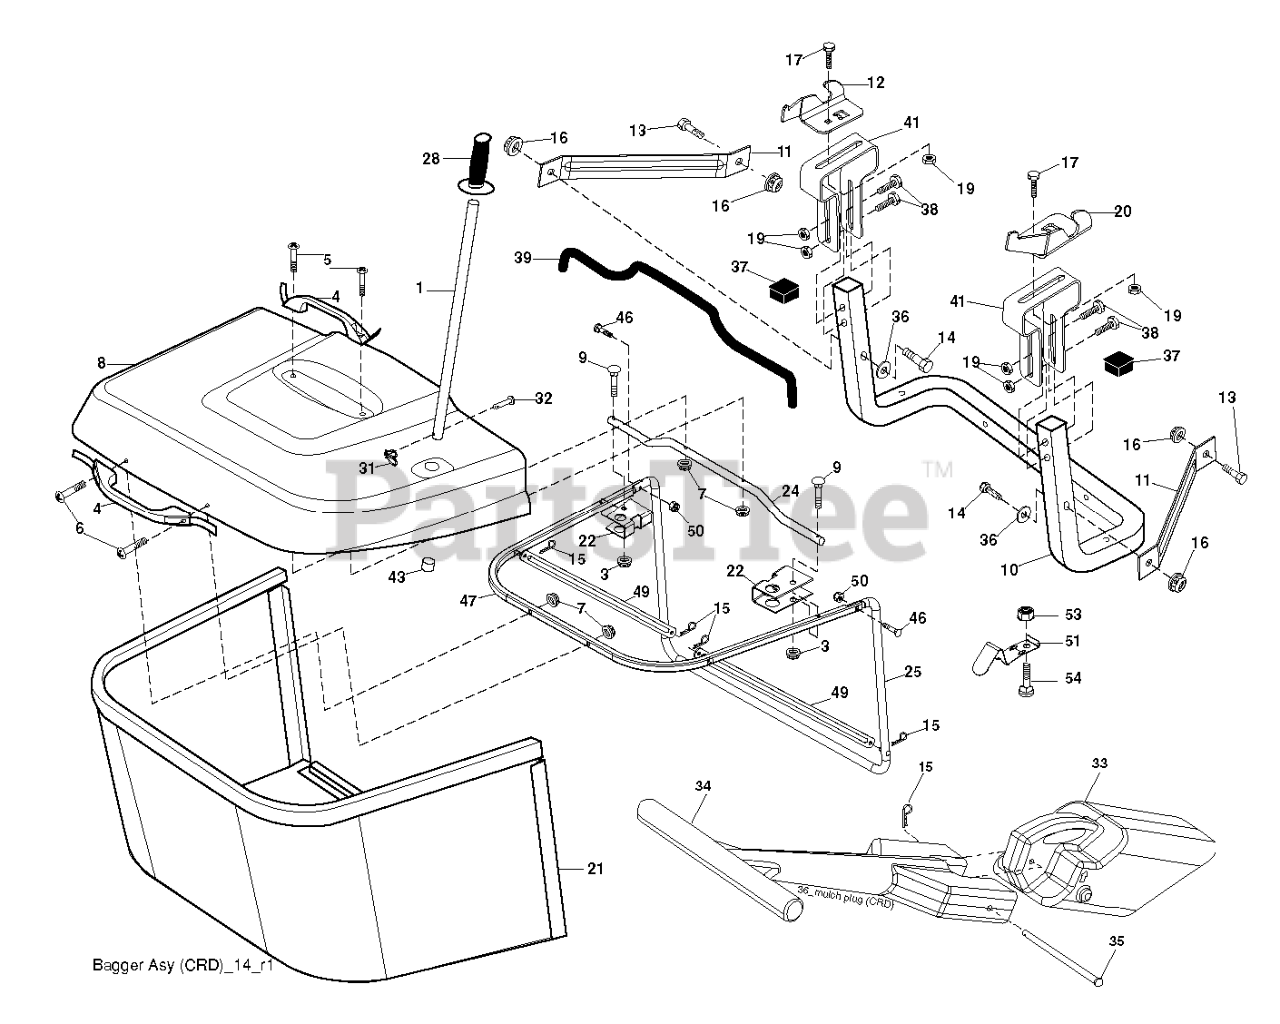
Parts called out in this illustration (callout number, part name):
1	TUBE.HANDLE.BAGGER.CRD/SRD.BLA
3	NUT T
4	HANDLE.BAGGER.W/LVRS.BLK.CRD
5	SCREW.PAN.HEAD
6	REPL BY 532 75 00-29
8	COVER.PNT.BGR.CRD.WSLOTS.MS668
9	Bolt Carriage 1/4-20 x 2.25d x Gr.5
10	TUBE
11	BRACKET.SUPPORT.UPPER.BAG.CRD
12	BRKT PIVOT
14	BOLT-HEX EAK
15	RETAINER-SPRNG RB
16	NUT LOCK FLG 3/8-16 UNC
17	RP BOLT 5/16-18 X3/4 ZN/YEL GR
19	NUT LOCK HEX FLANGE 5/16-18
20	BRKT.PIVOT.RH.CRD
21	BAGGER.ASM.CRD.2007
22	BRKT.SIDE.BAG.CRD
24	TUBE.PIVOT.BAG.CRD.BLACK
25	PIPE
28	GRIP.HANDLE.BLACK
31	RETAINER CLIP
32	RIVET,DRILLED
33	MULCHING.PLUG.107.CRD.(2 2)
34	HANDLE.MULCHER.92.CRD (2 2)
36	WASHER
37	Plug Support Bagger CRD
38	BOLT.5/16-18X2.5
39	SEAL.BAGGER.CRD
41	BRKT.VERT.ADJ.BAGGER.CRD
43	PLUG, TUBING END
46	BOLT.CARRIAGE.5/16-18
47	PIPE
49	ROD
51	LATCH
53	NUT
54	BOLT
